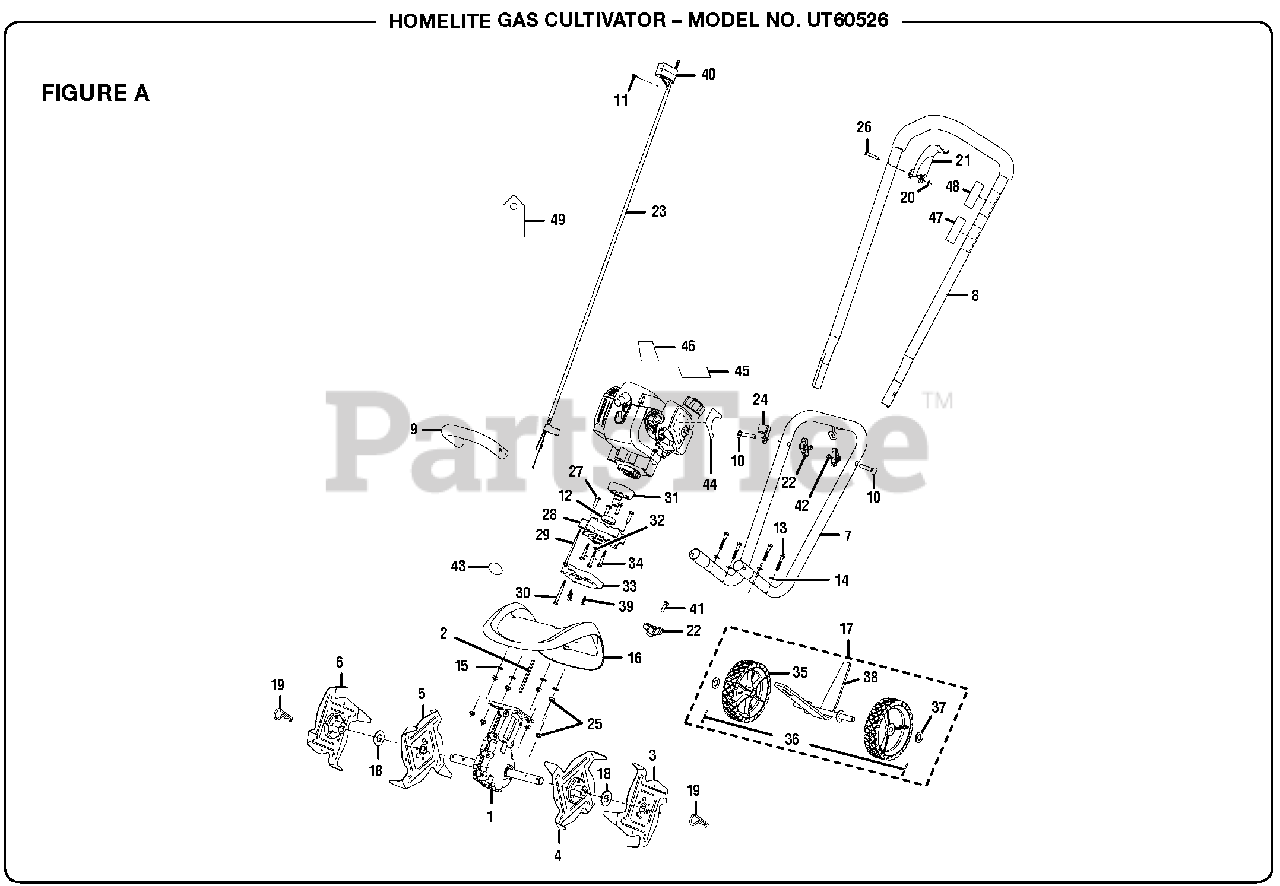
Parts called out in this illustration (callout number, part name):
1	Gear Box Assembly
2	Drive Shaft
3	Tine A, Outer Right
4	Tine B, Inner Right
5	Tine C, Inner Left
6	Tine D, Outer Left
7	Lower Handle
8	Upper Handle Assembly
9	Front Handle
10	Carriage Bolt (M8 x 60 mm)
11	Screw (8-16 x 1/2 in.)
12	Ball Bearing (6003zz)
13	Bolt (1/4-20 x 1.5 in.)
14	Washer (Curved)
16	Tine Shield Assembly
17	Wheel/Drag Stake Assembly (Incl. Key No. 35-38)
18	Felt Washer
19	Clevis Pin
22	Knob (M8)
23	Throttle Cable Assembly (Incl. Key No. 40)
24	Cable Clip
25	Lock Nut (1/4-20)
27	Bolt (1/4-20 x 1 in.)
28	Engine Adapter
29	Screw (M4 x 95 mm)
30	Screw (M5 x 60 mm T.F.)
31	Clutch Drum
33	Plate Adapter
34	Screw (M5 x 40 mm T.F.)
35	Wheel Assembly (6 in. Dia.)
36	Cotter Pin
38	Frame Assembly
39	Screw (M5 x 19 mm Pan Hd.)
41	Bolt (M8 x 25 mm Hex Hd)
42	Hex Nut (M8)
43	Foot Warning Label
44	Starting Label
45	Combustion Warning Label
46	Model Label
47	Warning Label
48	Icon Warning
